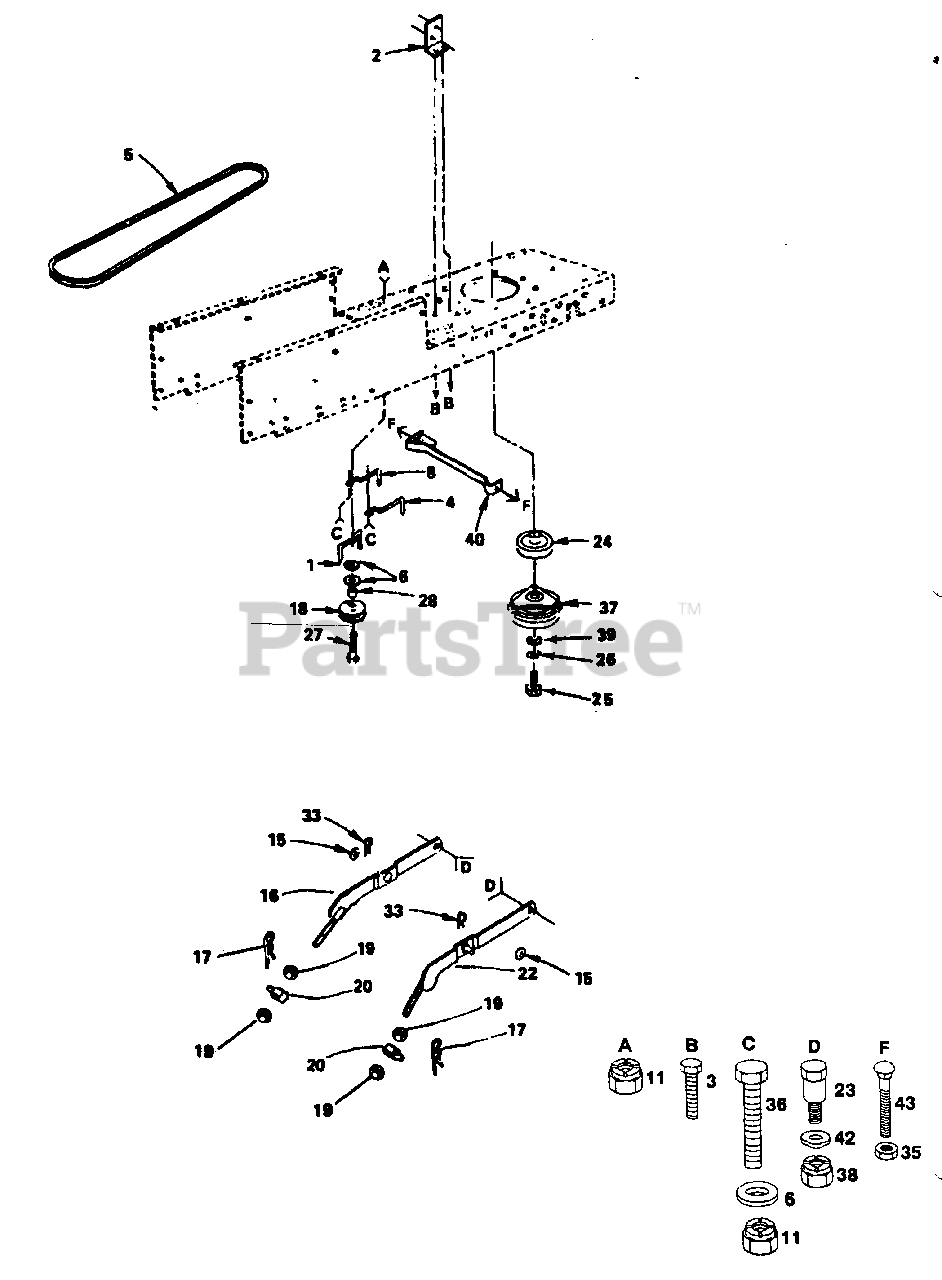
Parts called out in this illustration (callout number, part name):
1	Retainer, Belt (AYP part number)
2	Bracket, Switch (AYP part number)
3	Screw, Tapping, Hex Head 10-24 x 1/2 (AYP part number)
4	Keeper, Belt, Engine (AYP part number)
5	V-Belt, Drive (AYP part number)
6	Washer 13/32 x 13/16 x 12Gauge (AYP part number)
8	Keeper, Belt, Engine (AYP part number)
11	Nut, Crownlock 3/8-16
15	Washer 17/32 x 15/16 x 16 Gauge (AYP part number)
16	Arm Assembly, Suspension, L.H. (AYP part number)
17	Retainer, Spring (AYP part number)
18	Idler, Flat (AYP part number)
19	Nut, Hex 1/2-13 (AYP part number)
20	Trunnion, Lift, Lower (AYP part number)
22	Arm Assembly, Suspension, R.H. (AYP part number)
23	Bolt, Shoulder 3/8-16 (AYP part number)
24	Pulley, Engine (AYP part number)
25	Bolt, Hex M10-1.5 x 110 (AYP part number)
26	Washer, Lock 7/16 (AYP part number)
27	Bolt, Hex 3/8-16 x 2-3/4 (AYP part number)
28	Spacer (AYP part number)
33	Spring, Retainer (AYP part number)
35	Locknut 5/16-18
36	Bolt, Hex 3/8-16 x 1 (AYP part number)
37	Clutch, Electric (AYP part number)
38	Nut, Centerlock, Flange 3/8-16 (AYP part number)
39	Washer 1-1/2 x 15/32 x 1/4 (AYP part number)
40	Locater, Clutch (AYP part number)
42	Washer, Spring (AYP part number)
43	Bolt, Carriage 5/16-18 x 3/4
